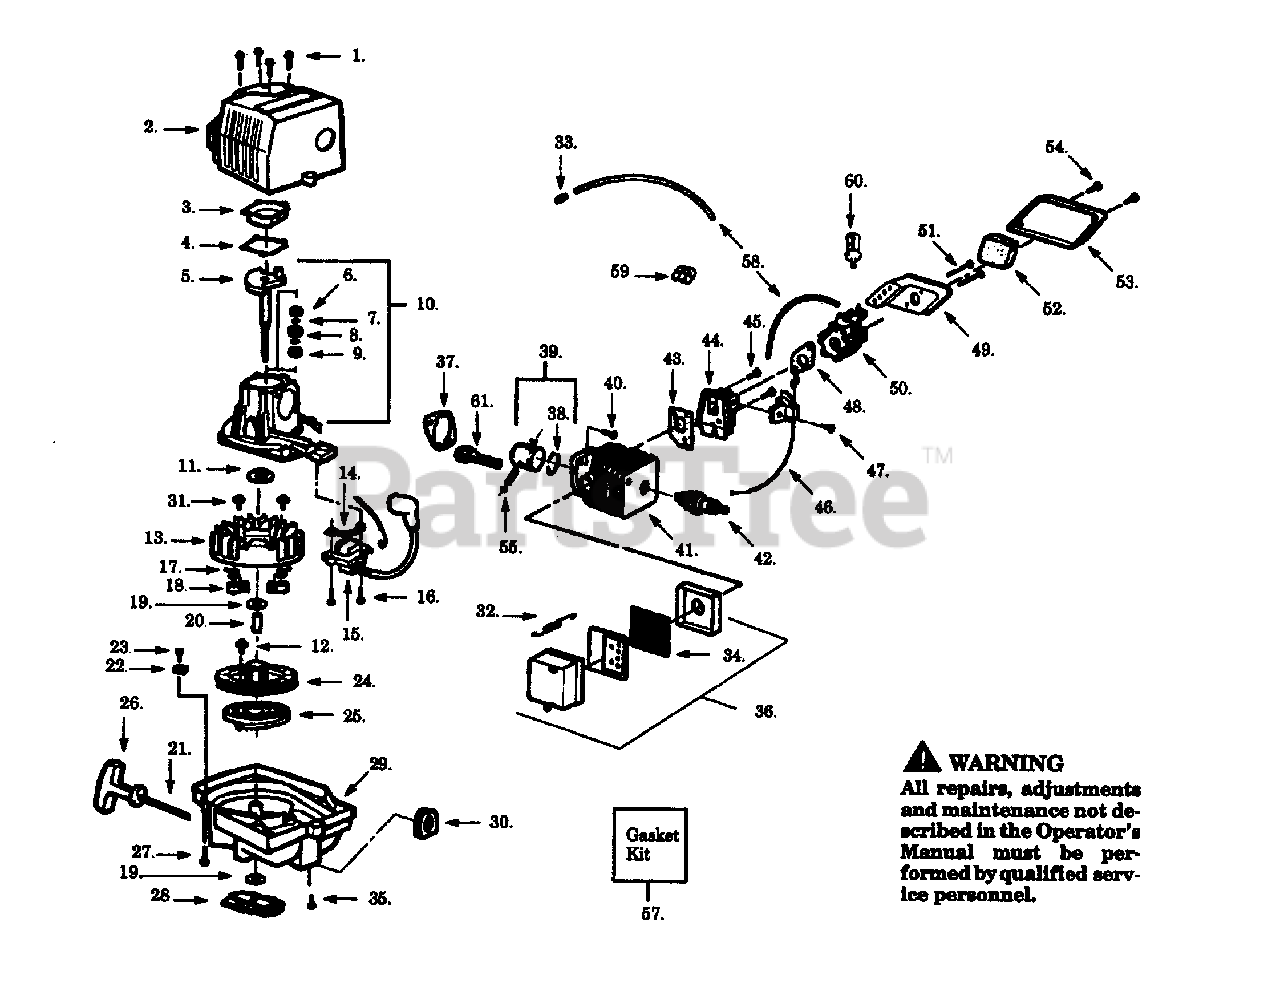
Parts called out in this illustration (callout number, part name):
1	SCREW - SHROUD
3	COVER-CRANKCASE
4	GASKET, CRANKCASE
5	CRANKSHAFT
6	BEARING
8	SEALING RING
10	CRANKCASE ASSY
11	RETAINING RING
13	FLYWHEEL
14	SPACER - IGNITION MODULE
15	IGNITION MODULE
17	STARTER DOG SPRING
19	WASHER FLAT
23	SCREW-10-16 X 1/2 HI-LO
24	STARTER PULLEY
25	SPRING-STARTER
26	HANDLE-STARTER
27	SCREW-10-14 X 13/16 (PL
32	MUFFLER SPRING
33	FUEL LINE FITTING
34	SPARK ARRESTOR
37	GASKET - CYLINDER
38	PISTON RING
42	SPARK PLUG (RCJ-8Y) NLA
44	ADAPTOR
45	SCREW - CARB. ADAPTOR
46	THROTTLE WIRE
47	SCREW 8-16 X 9/16 (PLAS
48	GASKET - CARBURETOR
52	AIR FILTER ELEMENT
54	SCREW-10-14X5/8 PHIL.FI
55	WRIST PIN RET.
57	GASKET KIT
58	KIT-LINE(FUEL)
60	FUEL PICK UP ASSY
61	CONNECTING ROD ASSEMBLY
5300353-06	CARBURETOR
5300693-50	PISTON ASSEMBLY
5300696-13	PISTON KIT 18CC
5300696-14	CYLINDER-18CC
5300696-19	CYLINDER
5300696-82	KIT-CARB ASSY WT-379
